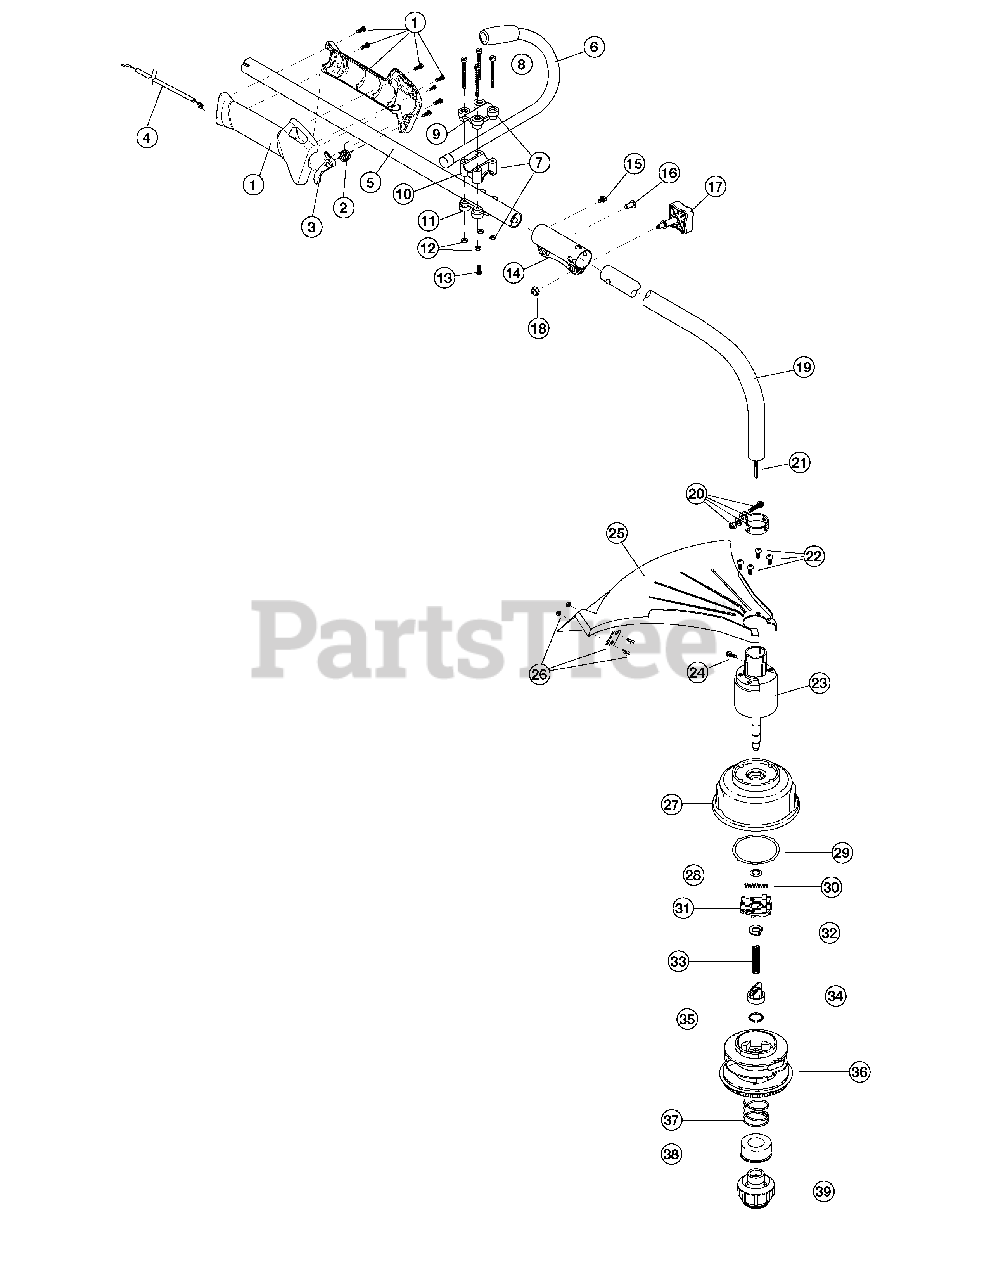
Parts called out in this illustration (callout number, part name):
1	Throttle Housing Assembly (includes 2 & 3)
2	Throttle Trigger Spring
3	Throttle Trigger
4	Throttle Cable
5	Upper Drive Shaft Housing
6	J-Handle Assembly
7	Handle Bracket Assembly (includes 8-13)
9	Upper Handle Clamp
10	Middle Handle Clamp
11	Lower Handle Clamp
13	Anti-Rotation Screw
14	Split Boom Coupler (includes 15-18)
17	Adjustment Knob
18	Knob Retaining Nut
19	Lower Drive Shaft Housing
20	Lower Clamp Assembly
21	Lower Flexible Drive Shaft
22	Shield Mounting Screw
23	Bushing Housing Assembly
24	Anti-Rotation Screw
25	Shield Assembly (includes 26)
26	Blade Assembly
27	Outer Spool Assembly (includes 28)
28	Retainer
29	Thrust Washer
30	Small Spring
31	Slider
34	Plunger
36	Inner Reel
37	Large Spring
38	Foam Seal
39	Bump Head Knob Assembly (includes 37 & 38)
